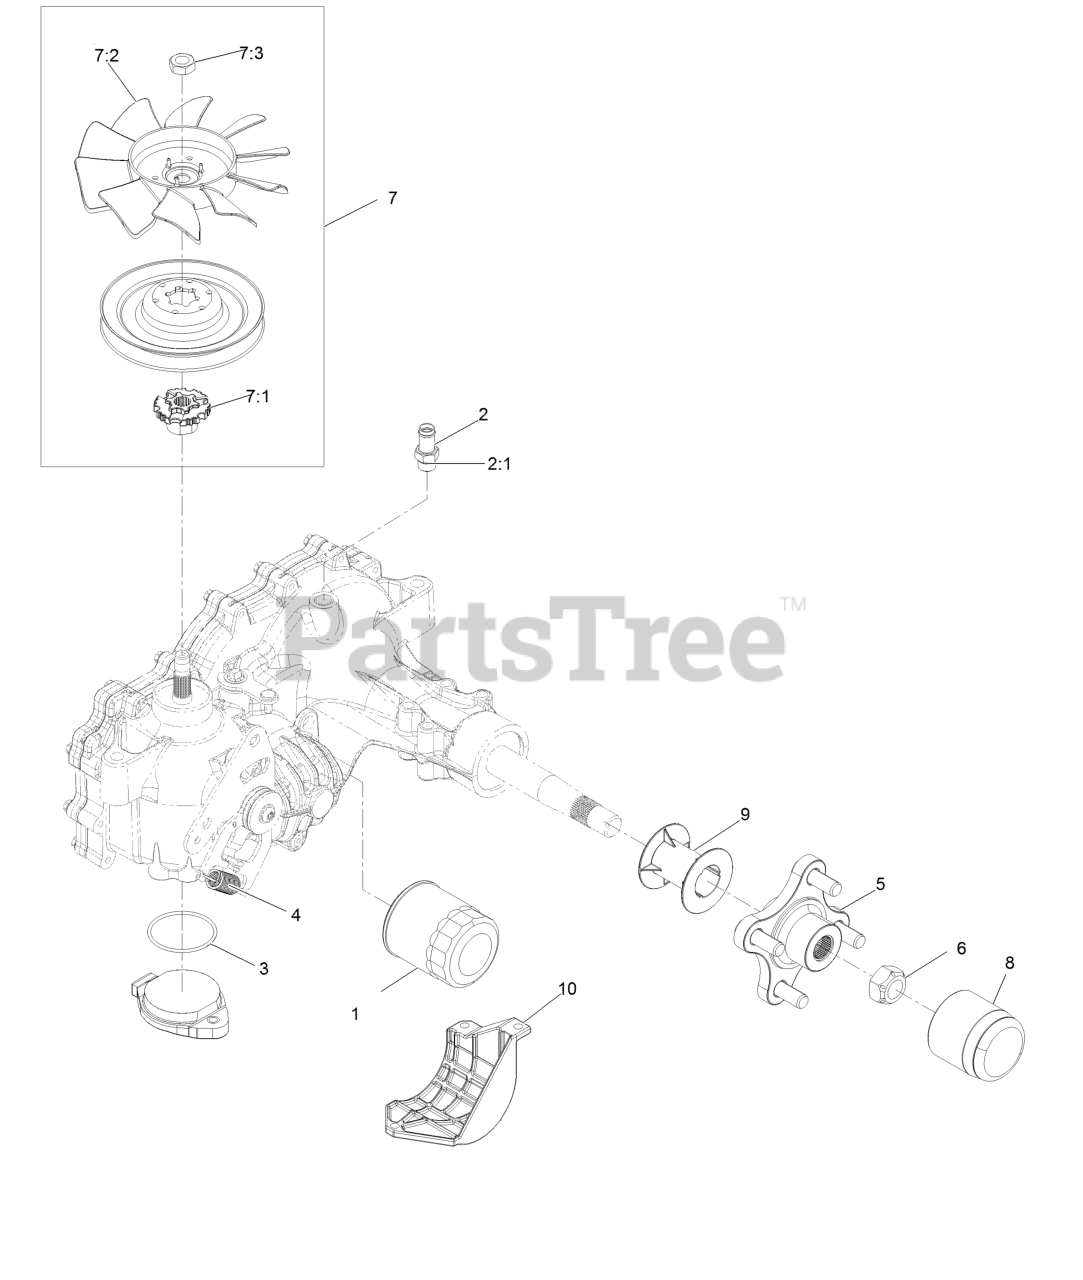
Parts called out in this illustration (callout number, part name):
1	Filter-Hydraulic
2	Adapter-Straight
2:1	O-Ring
3	O-Ring-Charge Seal Cover
5	Hub-Offset
6	Nut-Hub
7	Fan And Pulley Kit
7:1	Hub-Fan
8	Cap-Axle, Long
9	Tube-Axle
10	Guard-Filter, LH
11	Seal Kit
